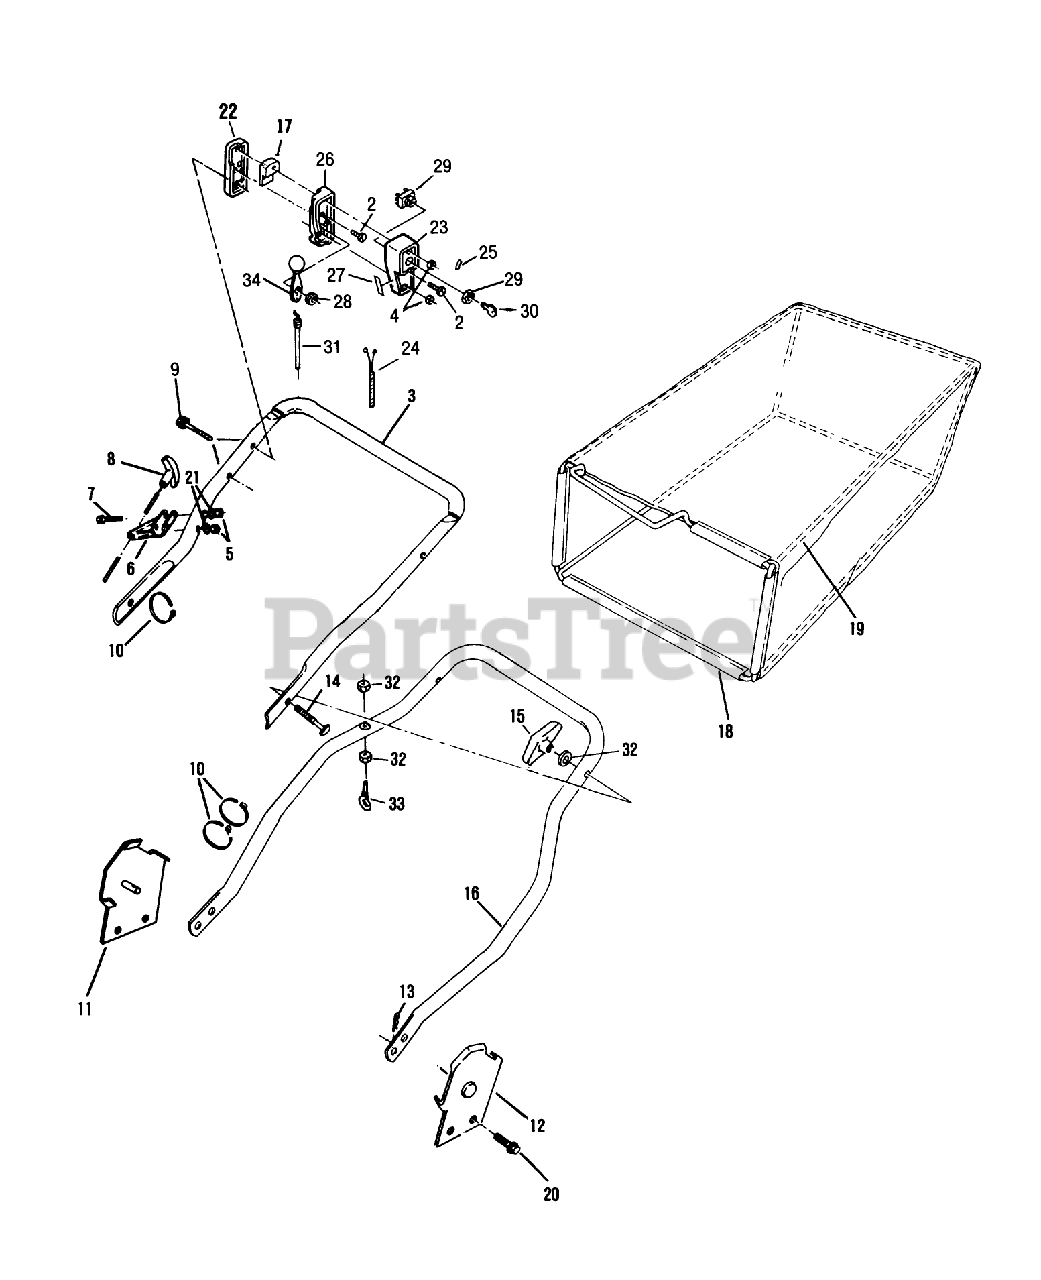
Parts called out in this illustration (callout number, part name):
2	SCREW
4	NUT C/LOCK E
5	LOCKNUT E
8	HANDLE START UM&D
9	SCREW
13	HAIR PIN
14	BOLT QUALITY
15	NUT-WING
21	WASHER
28	WASHER-SPRING
29	SWITCH AY
31	CABLE THROT WES
32	WASHER-CURVED
33	EYE BOLT WAS MFG
34	LEVER&KNOB AY WES
